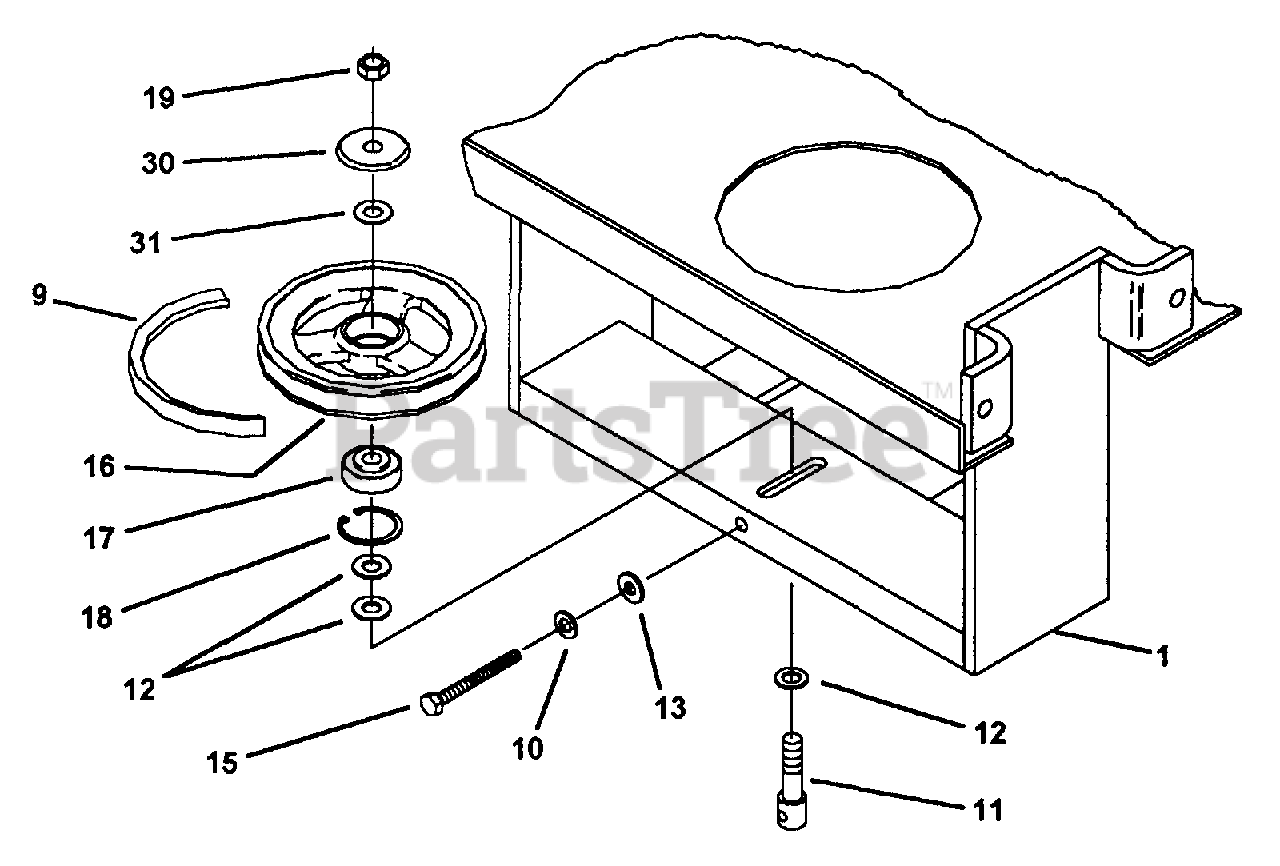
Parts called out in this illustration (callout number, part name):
1	MOTOR MOUNT WELDMENT
9	BELT, A-80 KEVLAR, MAIN DRIVE BELT
10	LOCKWASHER, 5/16" SPLIT SPRING
11	STUD, ADJUSTABLE
12	WASHER, FLAT STD. 1/2"
13	WASHER, FLAT STD. 5/16"
15	CAPSCREW, 5/16-18 X 3" GR.2 FULL THRD.
16	IDLER PULLEY ASSEMBLY
17	BEARING, WIDE INTER-RACE
18	SNAP RING,INTERNAL 40mm BORE
19	LOCKNUT, 1/2-13, NYLOC
30	WASHER, BEARING CAP
31	WASHER, 1/2" NOM. TYPE B NARROW
